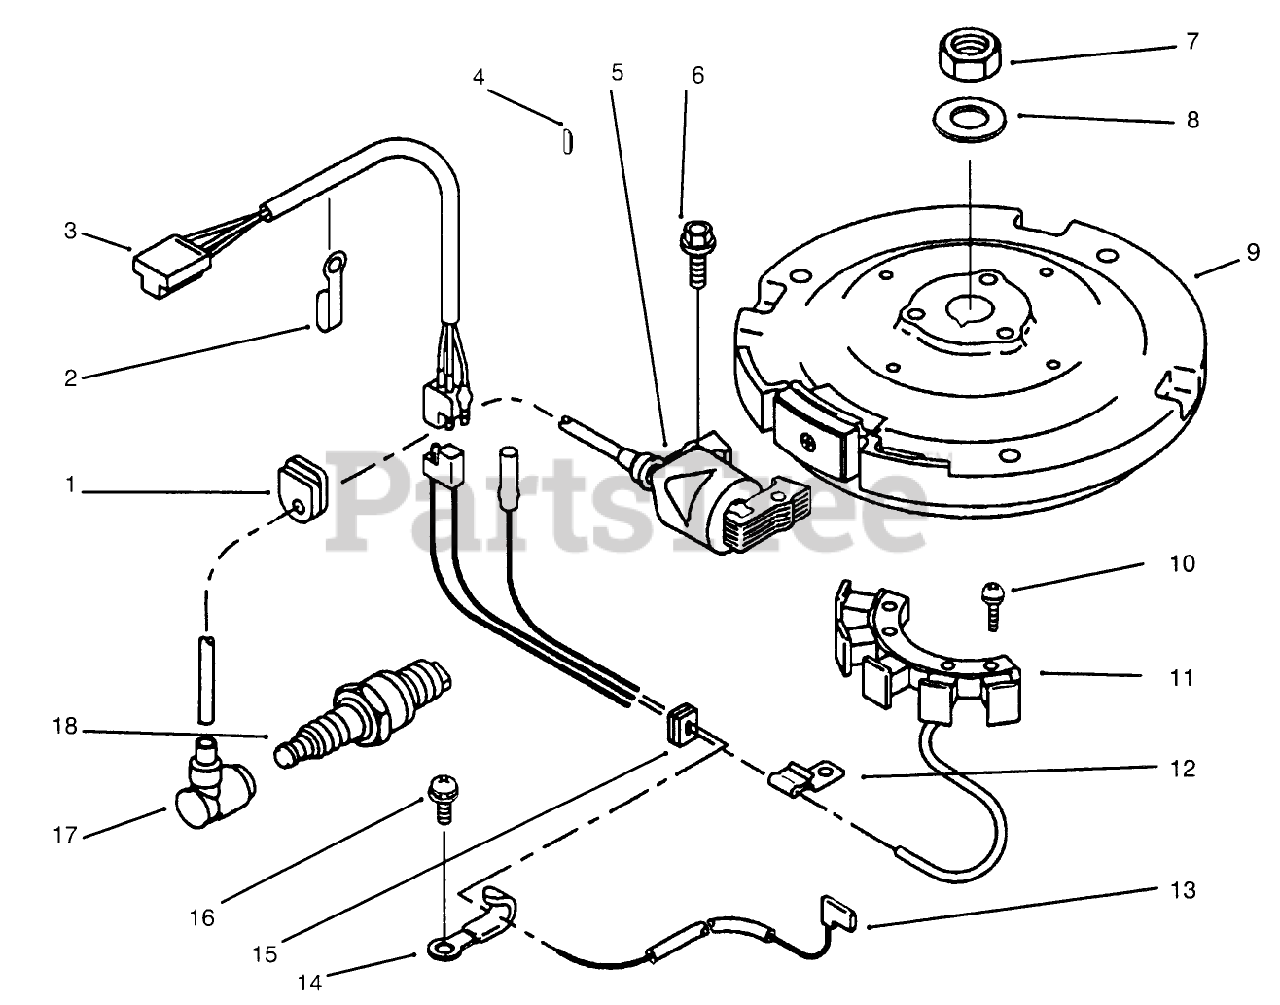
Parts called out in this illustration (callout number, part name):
1	Grommet
2	Clamp
3	Harness
4	Key
5	Coil-Ignition
6	Bolt-Flange
7	Nut
8	Washer
9	Flywheel-Complete
10	Screw
11	Coil-Charging
12	Clamp
13	Wire-Lead
14	Clamp
15	Grommet
16	Screw
17	Cap-Spark
18	Spark Plug-Rcj8
